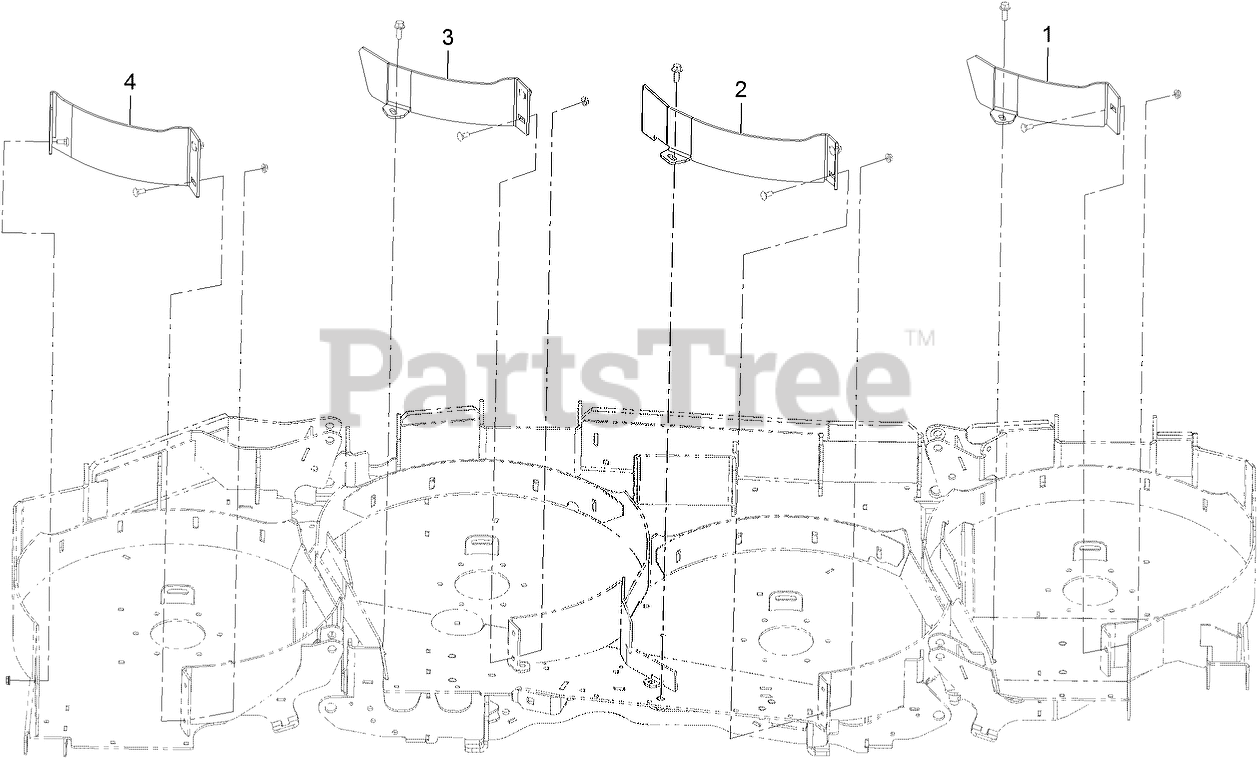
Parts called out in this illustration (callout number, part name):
1	BAFFLE-BLOCK, LH WING
2	BAFFLE-BLOCK, LH CTR
3	BAFFLE-BLOCK, RH CTR
4	BAFFLE-BLOCK, RH WING
